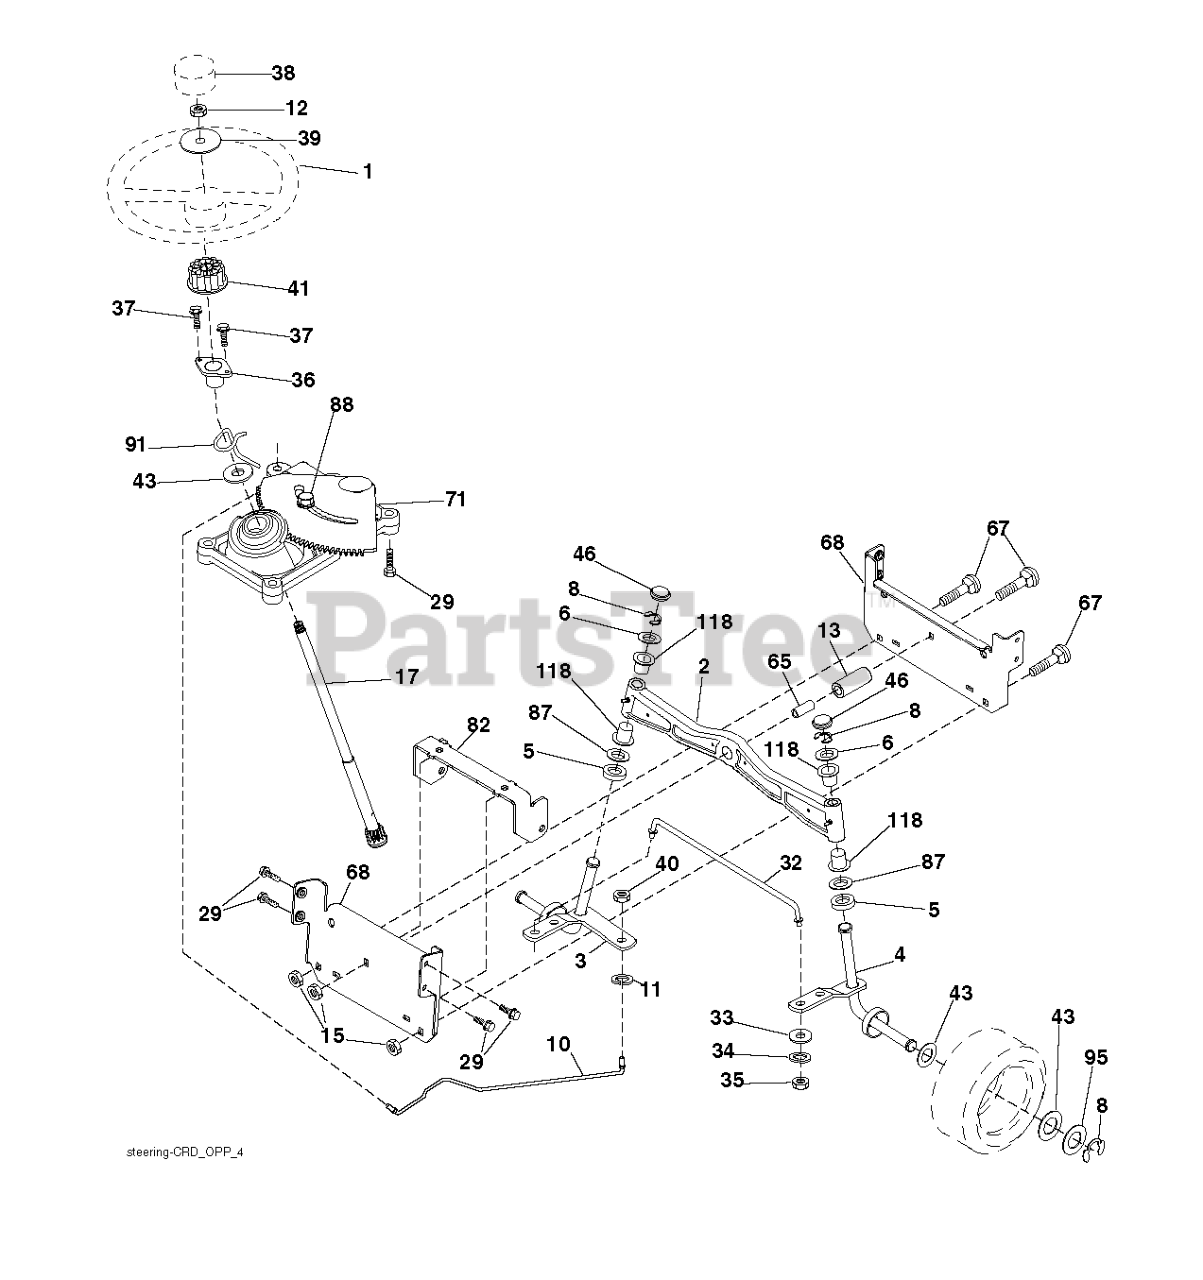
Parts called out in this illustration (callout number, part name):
1	RP WHEEL.STEER.HUSQ.PREM.OVMLD
2	AXLE.ASM.LT.CAST.LGHTWGHT
3	SPINDLE.ASM.LH.15"TIRES
4	SPINDLE.ASM.RH.15"TIRES
5	THRUST WASHER
10	DRAGLINK.15".TIRES.2001
11	WASHER, LOCK 3/8
12	NUT.HEX.1/2-20
13	TUBE, PIVOT AXLE
15	NUT LOCK FLG 3/8-16 UNC
17	SHAFT ASM STRG
29	SCREW, 3/8-16X3/4
33	WASHER M
34	WASHER.LOCK.HVY.HLCL.SPR.5/16
35	NUT, CROWNLOCK
36	BUSHING, STRG. BLK
37	SCREW.TT.#10-32X.5.3/8.FLANGE
38	RP INSERT.CAP.WHL.STRG.HUSQ.
39	WASHER 9/16"ID, 2 3/8"OD
40	NUT CROWNLOCK 3/8-24
41	ADAPTER, WHEEL STNG..
46	CAP.SPINDLE.BLACK
65	SPACER.BRACE.AXLE
67	BOLT CARRIAGE
68	BRACE.AXLE.15"TIRES
71	STEERING ASM
82	BRACKET.SUSP.CHASSIS.FRONT.15
87	WASHER, FLAT .781 X 1 1/2"
88	BOLT, SHOULDER 7/16-20
91	CLIP.STEERING
95	WASHER.HARDENED
118	BUSHING, AXLE CAST
